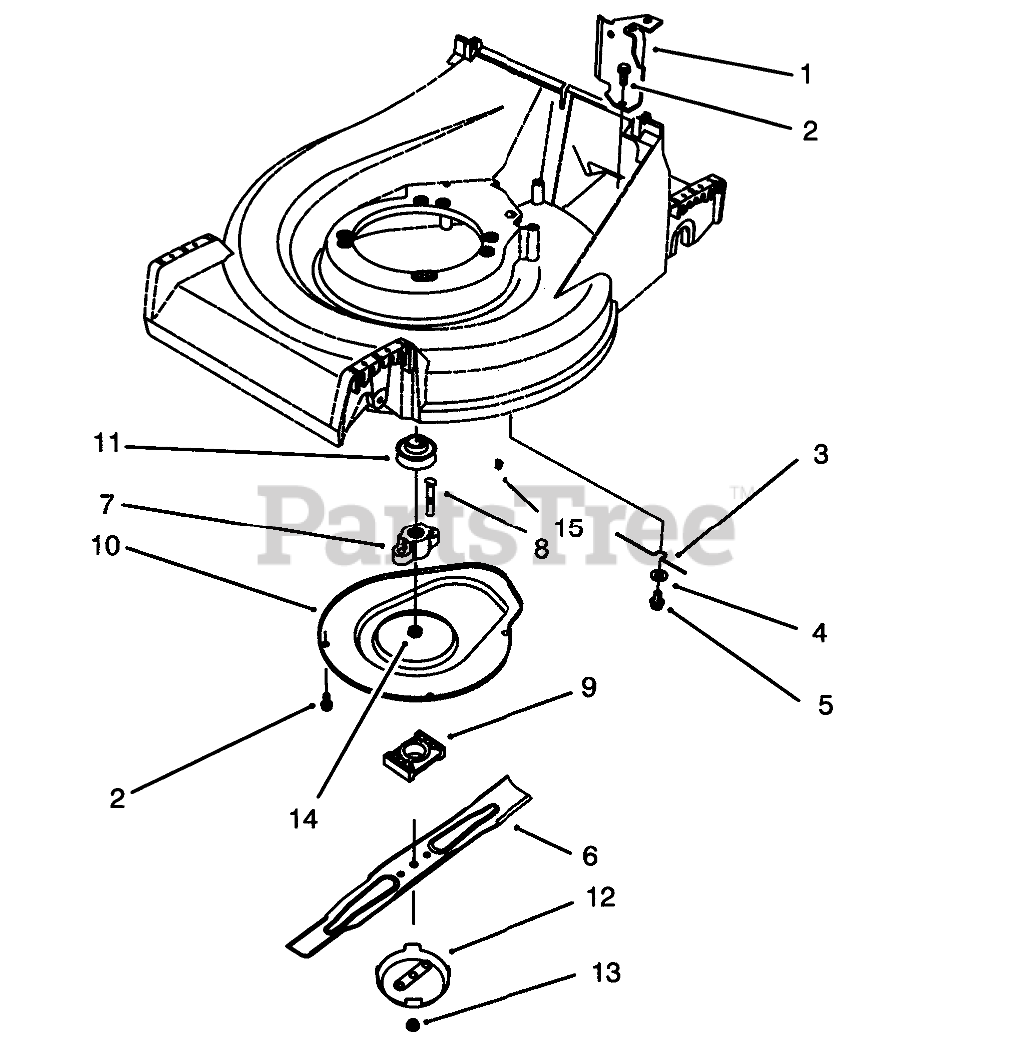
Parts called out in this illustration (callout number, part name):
1	Bracket-Cable Support
2	SCREW-HWHTF
3	RETAINER-BELT
4	WASHER-FLAT
5	SCREW-HHFTF
6	Key
8	BOLT-BLADE
9	SPACER-BLADE
10	Cover
11	PULLEY
12	CUP-SCALP, ANTI
13	NUT-LOCK
14	NUT-LOCK, NI
15	KEY-WOODRUFF
